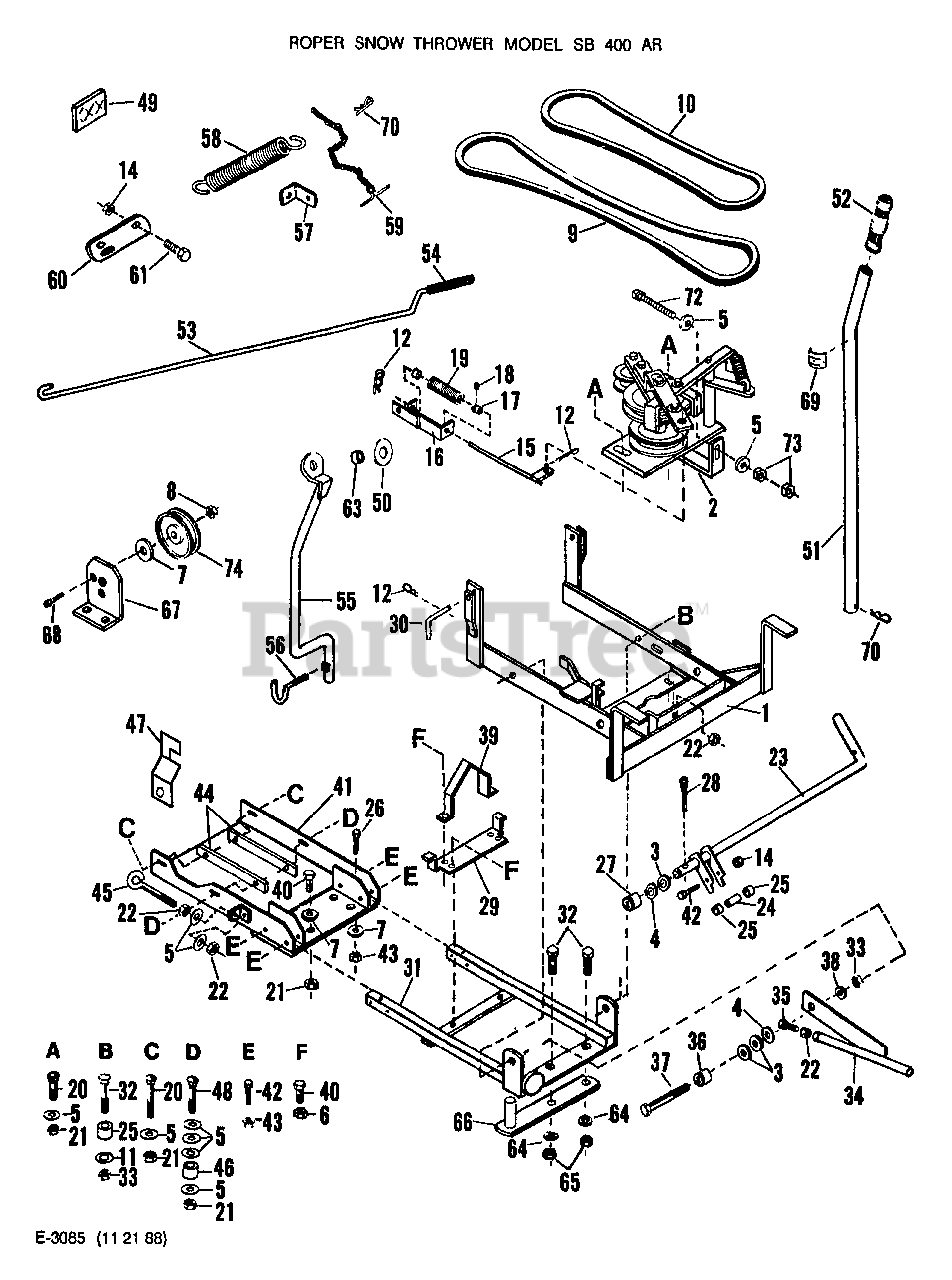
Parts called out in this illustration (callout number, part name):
1	ASSY-MOUNTING FRAME
2	ASSY-PULLEY MTG BRKT
4	SCREW 1/4-20 X .875
12	HAIR COTTER PIN
14	NUT & WASHER ASSY
15	ASSY-CLUTCH ROD
16	No Desciption for Part
18	No Desciption for Part
19	No Desciption for Part
21	NUT & WASHER ASSY
23	LIFT BAR ASSY
29	UPSTOP EXTENSION
30	CLEVIS PIN
31	MTG FRAME ASSY
34	LIFT EXTENSION ASSY
39	UPSTOP BRKT
41	PIVOT BRKT CHANNEL ASSY
44	HEADER CHANNEL STRAP
49	TAIL REFLECTOR
50	CHUTE CONTROL DECAL
51	LIFT HANDLE ASSY
52	HANDLE GRIP
54	HANDLE GRIP
55	CRANK SUPPORT ASSY
56	CRANK ROD ANCHOR BRKT
58	LIFT SPRING
59	CHAIN & TOGGLE ASSY
62	CHUTE CONTROL DECAL
63	CRANK GUIDE BUSHING
66	CRANK ROD ANCHOR ASSY
67	IDLER PULLEY BRKT
70	HAIR COTTER PIN
74	IDLER PULLEY ASSY
